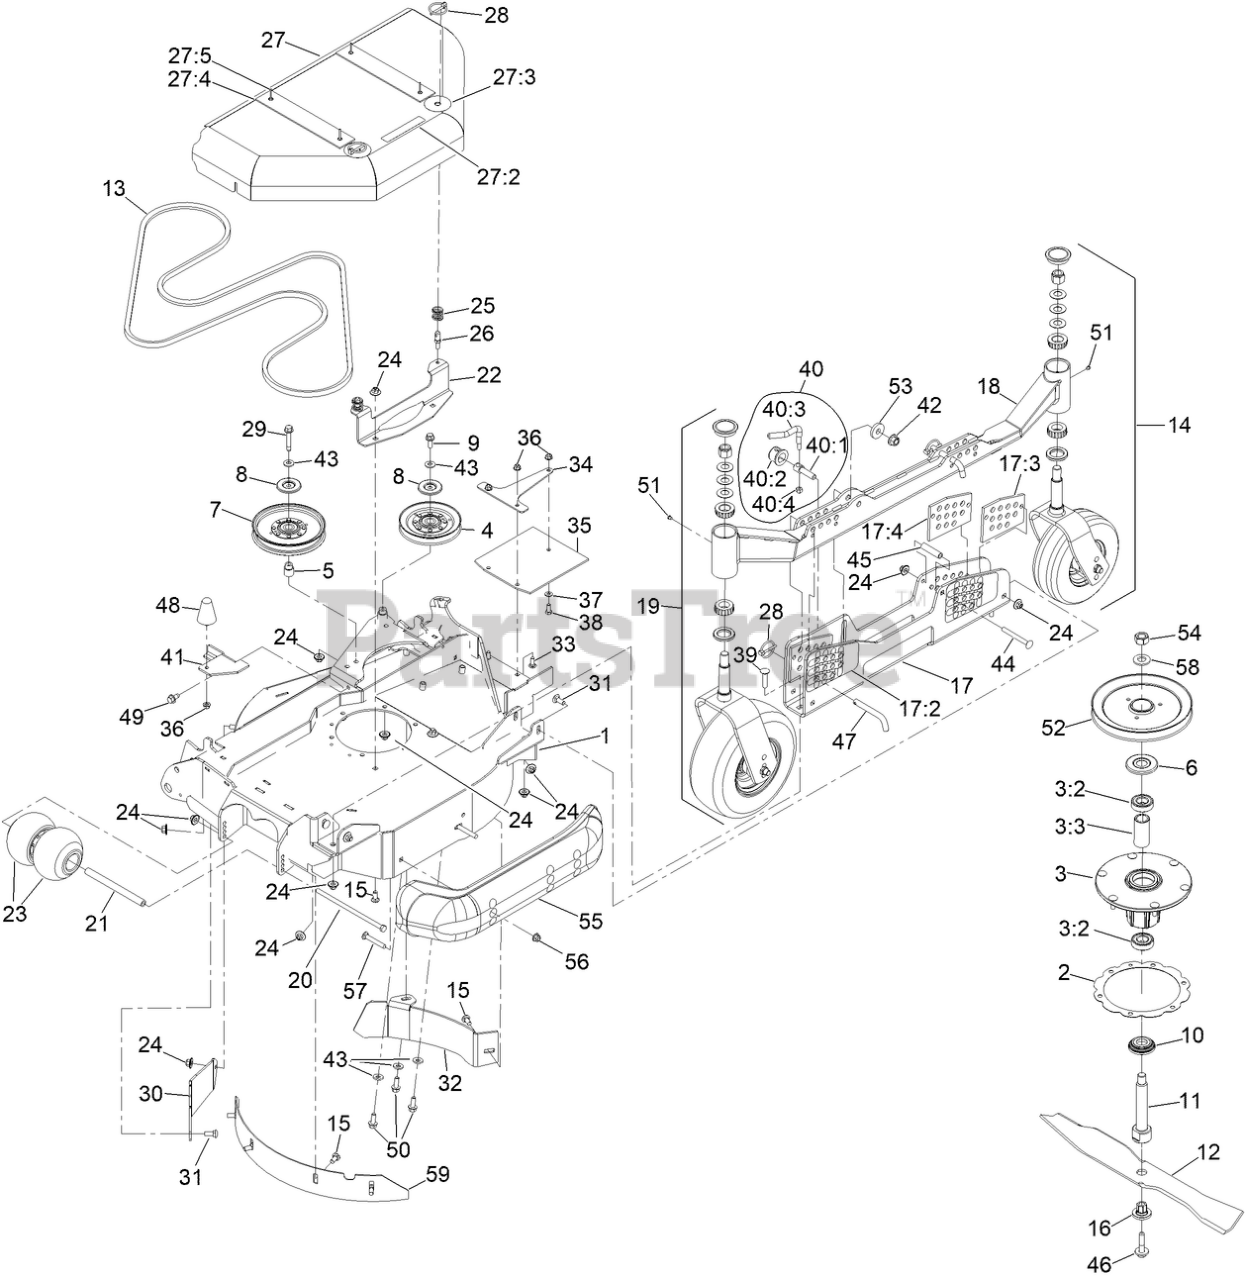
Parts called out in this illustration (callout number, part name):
1	LH WING DECK ASM
2	RING-SPACER, HOUSING
3	SPINDLE ASM
3:2	BEARING-BALL
3:3	SPACER-BEARING
4	IDLER-V
5	BUSHING-IDLER
6	GUARD-BEARING, TOP
7	IDLER-PULLEY
8	SHIELD-DUST
9	SCREW-HHF
10	GUARD-BOTTOM
11	SHAFT-SPINDLE
12	BLADE-24.50 MULCH
13	BELT-V
14	REAR CASTER WHEEL ASM
15	BOLT-CARR
16	BUSHING-HEX
17	LH HOC CHANNEL ASM
17:2	DECAL-HEIGHT OF CUT-LH
17:3	PLATE-GUIDE, HOC (LH)
17:4	PLATE-GUIDE, HOC (RH)
18	TUBE-HOC, LH
19	CASTER WHEEL ASM
20	SCREW-HH
21	SPACER-WHEEL
22	BRACKET-SHIELD MOUNT, OUTER
23	ROLLER-SCALP, ANTI
24	NUT-FLANGE, NI
25	SPRING
26	PIN, SPRING
27	LH WING SHIELD ASM
27:2	DECAL-NO STEP
27:3	DECAL-SCRATCH COVER
27:5	RIVET-POP
28	PIN-LYNCH
29	SCREW-HHF W/ PATCH
30	PLATE-FILL, LH DECK
31	BOLT-CARR
32	BAFFLE-BLOCK
33	SCREW-CARR
34	SUPPORT-FLAP, LH
35	GUARD-TIRE, LH
36	NUT-HF, NI
37	WASHER-PLAIN
38	SCREW-HH
39	SCREW-CARR
40	LEVER ASM
40:1	SCREW-LOCK
40:2	CAP-LOCK
40:4	NUT-LOCK, NI
41	BRACKET-COVER RETAINER
42	NUT-LOCK
43	WASHER-BELLEVILLE
44	SCREW-CARR
45	SPACER
46	SCREW-SEMS
47	PIN-HOC
48	BUMPER-RUBBER
49	SCREW-HWH
50	SCREW-HHF
52	SHEAVE-DRIVE, BLADE
53	WASHER
54	NUT-HEX
55	SKID-BUMPER, DECK
56	NUT-HF, NI
57	SCREW-CARR
58	WASHER
59	BAFFLE-DEPTH, LH
